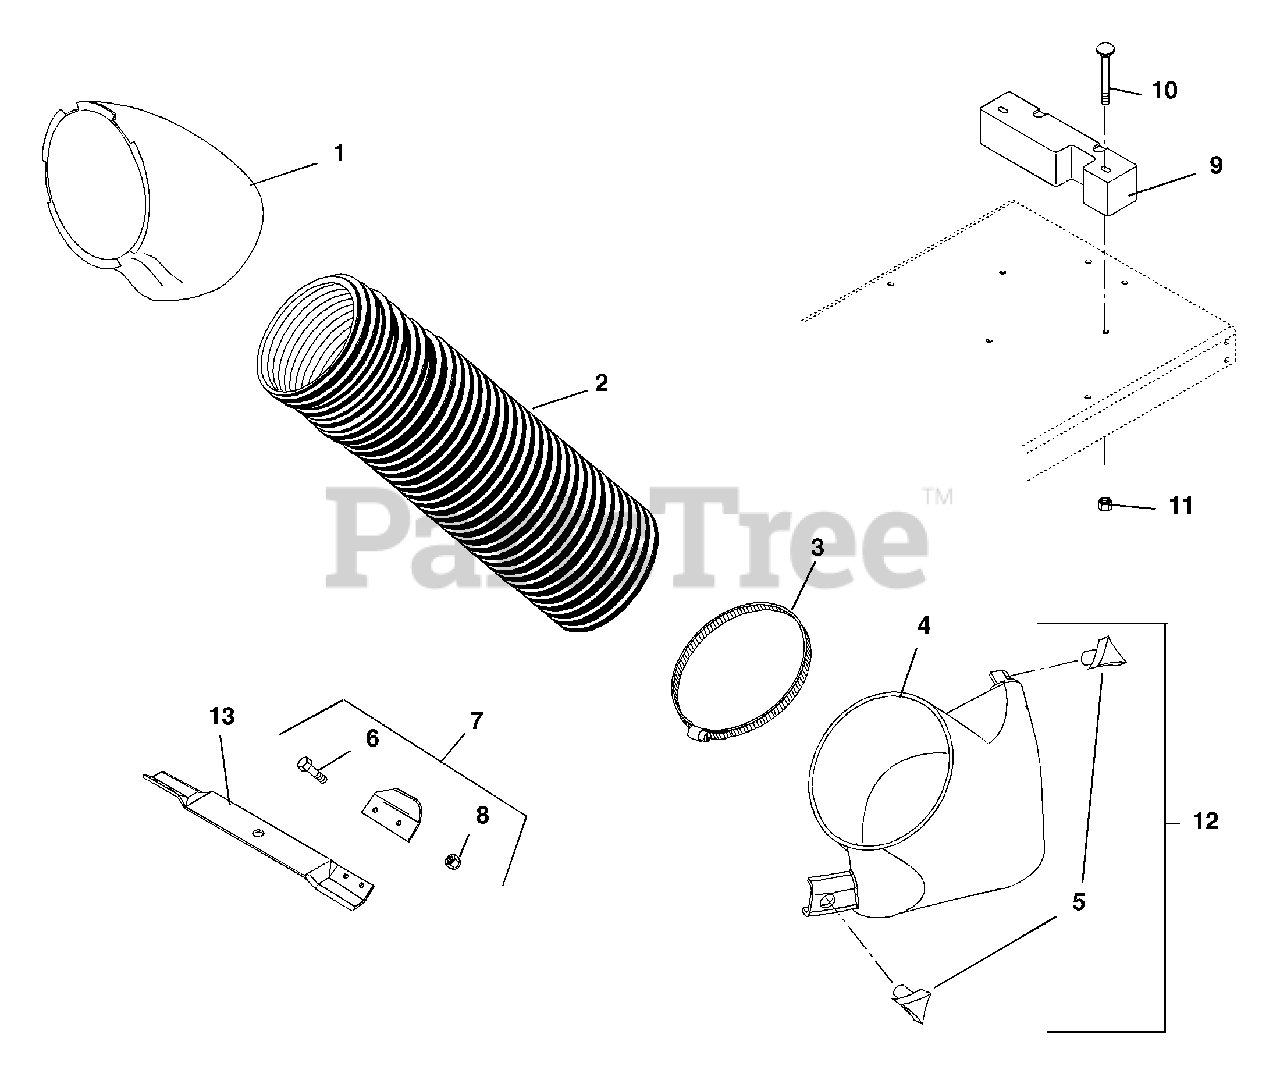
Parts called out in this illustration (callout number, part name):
1	BAGGER BOOT - UPPER
2	HOSE 7 X 45
3	CLAMP-HOSE WRM 2.13/8.62X.56
4	ASS'Y, MOWER BOOT W/DECAL
6	BLT-HEX .31-24X.75 GR8 YWZC
7	ASS'Y, VANE SERVICE
8	NUT-CTRLK .31-24 YWZC
9	COUNTER WEIGHT
10	@BLT-RDHDSQNK .44-14X4.50 G2YZ
11	@NUT-LK-CTR .44-14 YWZC
12	ASS'Y, MOWER BOOT 42"
13	BLADE, 22"
